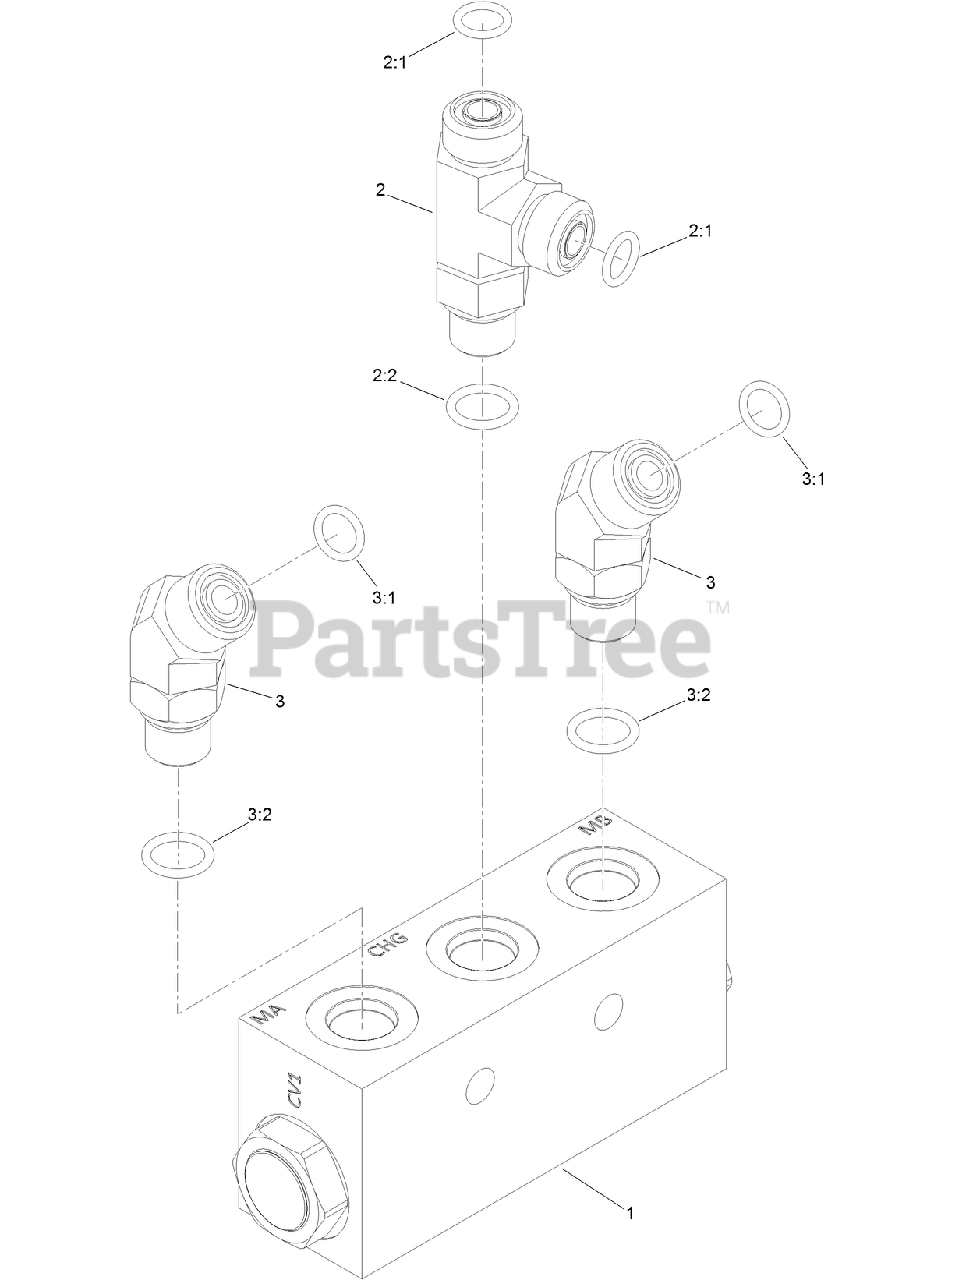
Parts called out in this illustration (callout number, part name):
1	MANIFOLD-CHECK, CHARGE
2	FITTING-TEE
2:1	O-RING
2:2	O-RING
3	FITTING-ELBOW, 45 DEG
3:1	O-RING
3:2	O-RING
